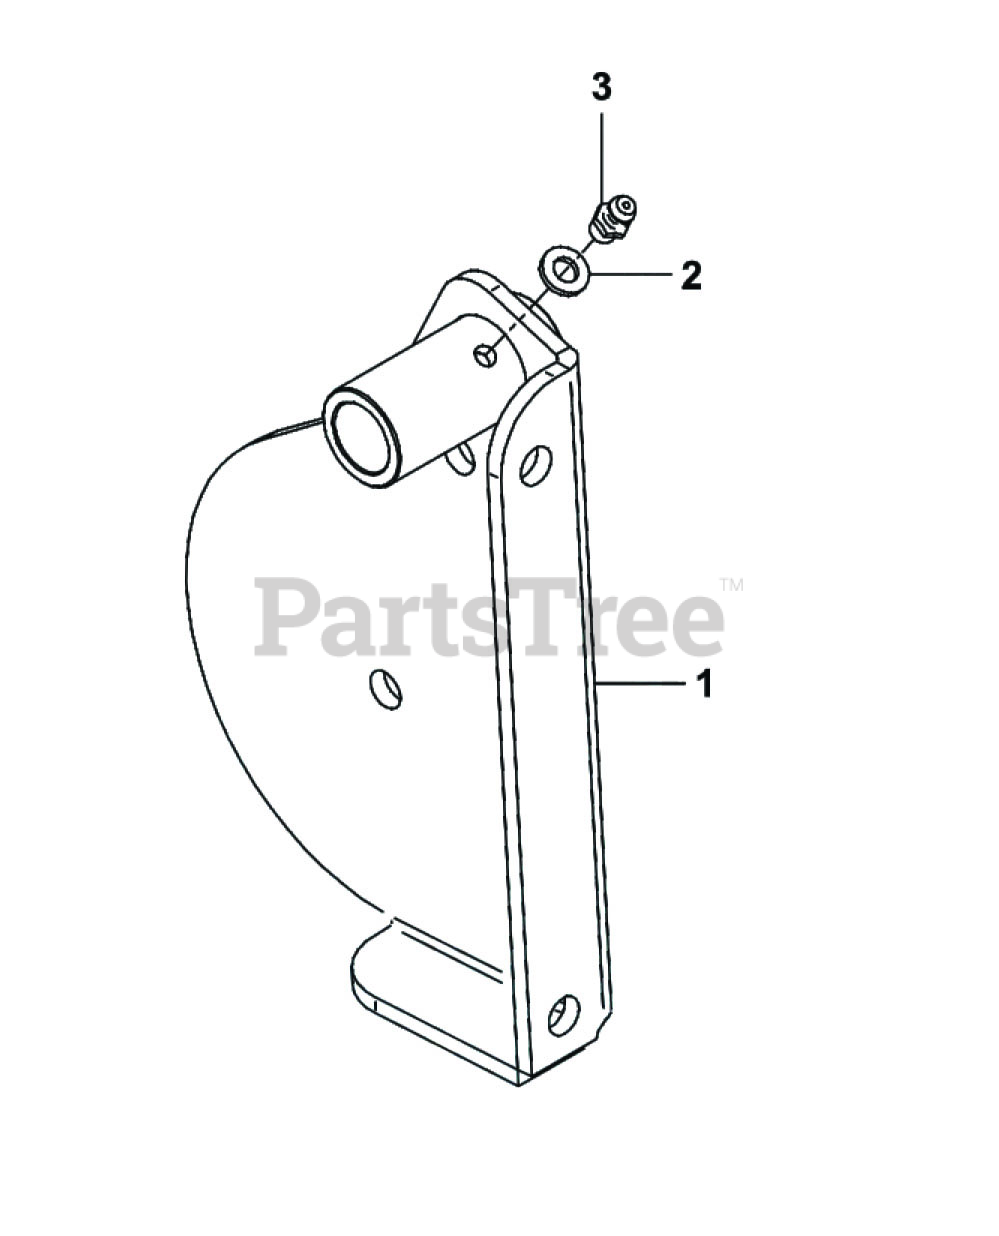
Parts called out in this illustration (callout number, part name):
1	IDLER ARM WELDMENT
2	FLAT WASHER M6 x 12
3	GREASE FITTING
